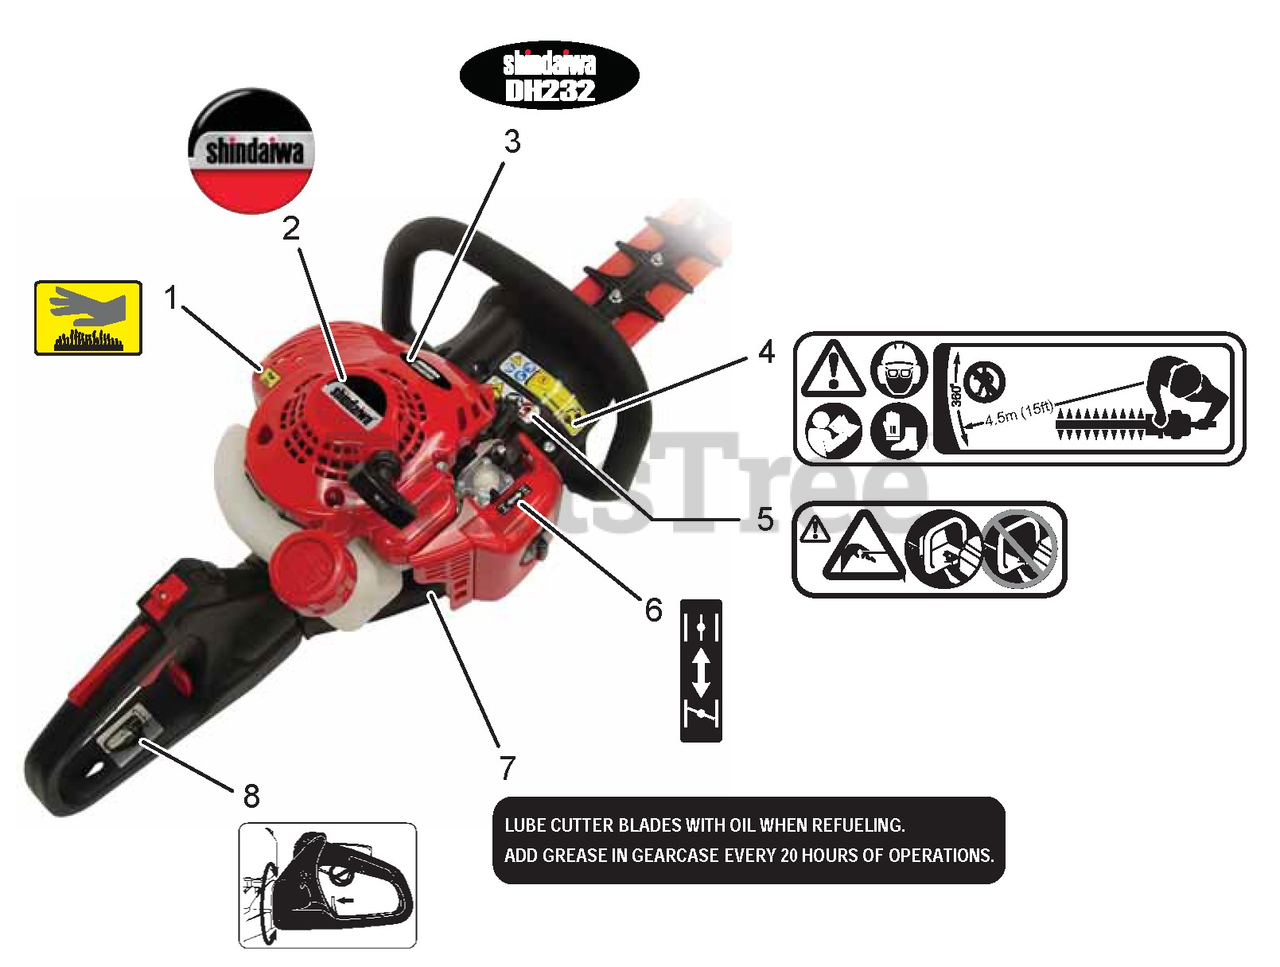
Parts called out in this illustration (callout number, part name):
1	LABEL - HOT SURFACE
2	LABEL - SHINDAIWA
3	LABEL - MODEL DH232
4	LABEL - CAUTION
5	LABEL - CAUTION
6	LABEL - CHOKE
7	LABEL - BLADE LUBRICATION
8	LABEL - CAUTION
